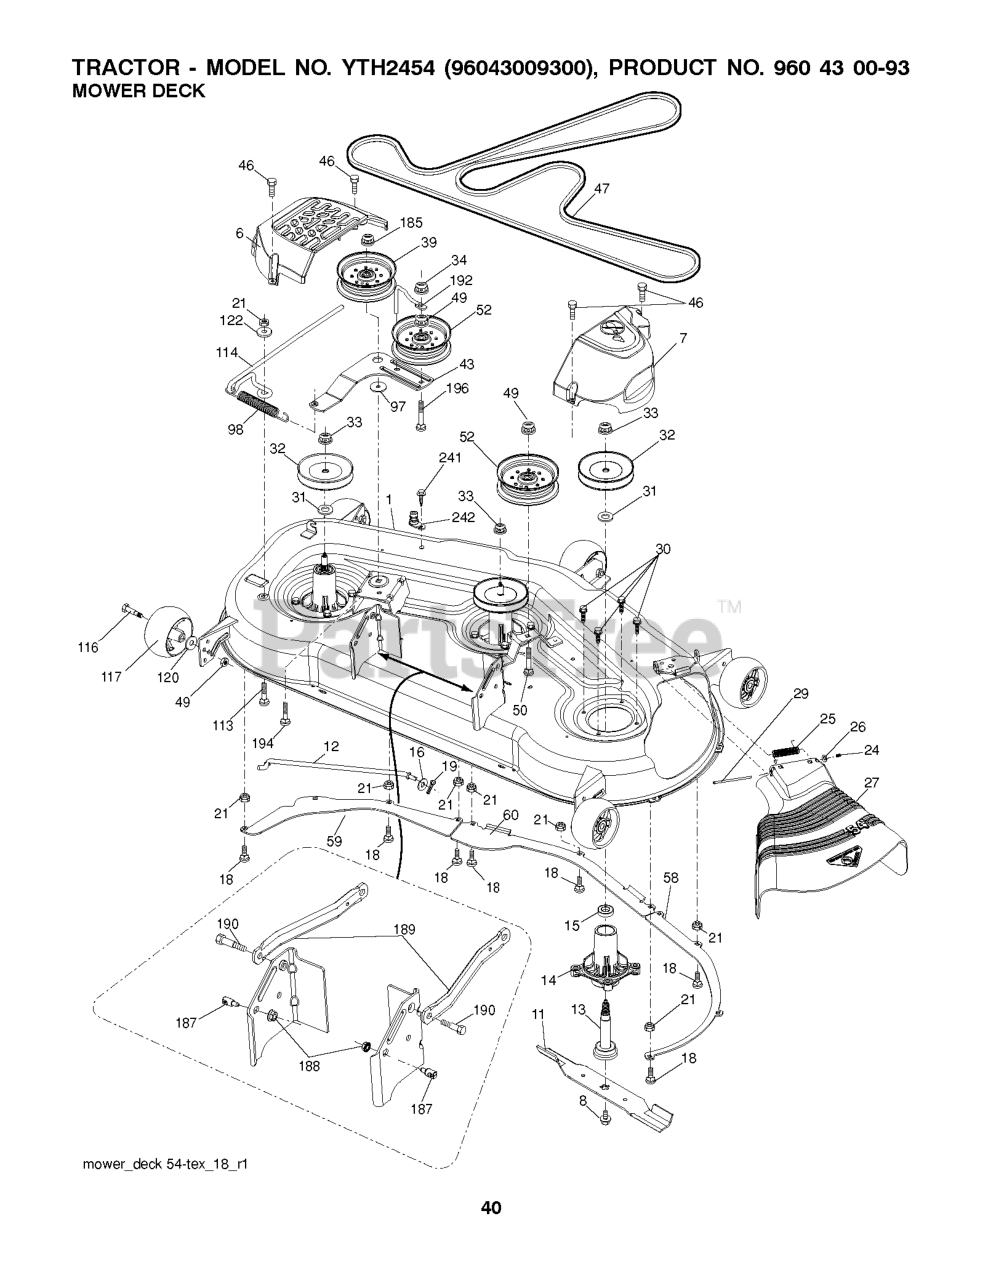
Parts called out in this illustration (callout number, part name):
1	DECK.WELDMENT.54"MS418
6	COVER.MANDREL.LH.54"20
7	COVER.MANDREL.RH.54.20
8	BOLT.WASHER.ASM.7/16-2
11	54" MULCH BLADE
11	BLADE.BAGGING.54"
12	ROD.ANTI.SWAY.48/54"K4
13	SHAFT ASM MANDREL
14	RP.HOUSING.MANDREL.4PT.
16	WASHER
18	BOLT
19	PIN.COTTER.5/16.BOW TI
21	LOCKNUT
24	CAP-SLEEVE LT
25	SPRING, TORSION
26	NUT PUSH M
27	DEFLECTOR
29	ROD.HINGE
30	SCREW, WASHER HEAD
31	WASHER.SPACER.MANDREL
32	PULLEY/MANDREL
33	NUT.FLANGE.LOCK.TOP
39	RB PULLEY.IDLER.4.50/HUB SPEC
46	SCREW.1/4-20X5/8
47	RP.BELT.DRIVE.54."2006
49	NUT LOCK FLG 3/8-16 UNC
52	PULLEY.IDLER.2006
58	BAFFLE.RIGHT.54"
59	BAFFLE.LEFT.54"
60	BAFFLE CENTER 54" MOWER
98	SPRING, DECK DRIVE
114	ROD TENSION RELIEF
116	BOLT.SHOULDER.3/8-16X3-5/8.
117	RP WHEEL. GUAGE RALLY
120	WASHER
122	BUSHING.RELIEF.TENSION
184	NUT LOCK HEX FLANGE 5/16-18
185	NUT.LOCK.FLANGE.7/16
187	STUD.FASTNER.W/ANTI-ROTATE
189	ARM.SUSPENSION.MOWER
190	BOLT.SHOULDER
192	KEEPER.BELT.IDLER.54"T
194	BOLT.CARR.SQNK.7/16
241	SCREW.TT.#10-32X.5.3/8.FLANGE
242	PORT.WASHOUT
